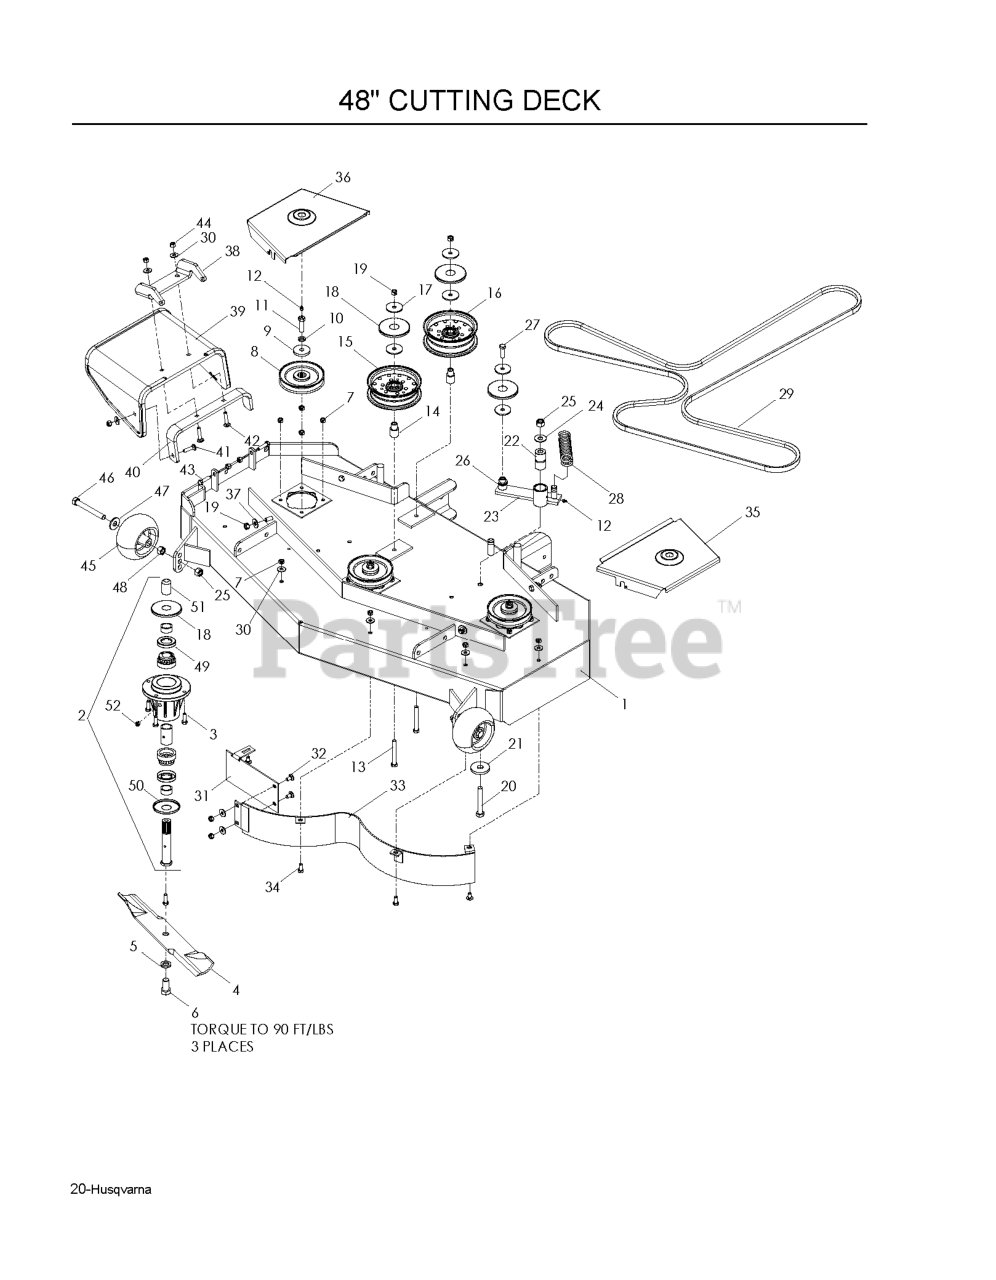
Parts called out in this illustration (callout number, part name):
1	DECK W/DECALS 48"
2	HOUSING ASM, 52/61
3	HCS 5/16C X 1
4	BLADE OEM 16 1/4"
5	LOCKWASHER 5/8
6	HCS 5/8F X 1 1/4
7	NUT 5/16C CENTERLOCK
8	PULLEY 42-48
9	SPINDLE WASHER
10	WASHER 7/16 LOCK
11	HCS 7/16-20 GD 8 SPEC
12	ZERK
13	HCS 3/8C X 3
14	IDLER BUSHING
15	IDLER PULLEY
16	IDLER PULLEY (TALL)
17	WASHER, 3/8 SPEC
18	TOP DUST CAP
19	NUT 3/8C CENTERBLOCK
20	HCS 1/2C X 3 1/4
21	WASHER, SUPPORT
22	PIVOT BUSHING
24	WASHER 1/2 FLAT
25	NUT 1/2-13 HEX NYLOC ZD
27	HCS 3/8C X 1 1/4 GR5
29	BELT, DECK
30	WASHER 5/16 FLAT
31	CENTER BAFFLE 48"
32	CARRIAGE BOLT 5/16C X 5/8"
33	MAIN BAFFLE - 48" DECK BLK
34	HCS 5/16C X 3/4
35	LT 48 SHIELD, ORG
36	RT 48 SHIELD, ORG
37	WASHER 3/8 FLAT
38	PIVOT BRACKET - CHUTE
39	CHUTE, RUBBER DISCHARGE WB
40	BRKT, REINF-CHUTE WB
41	BOLT, CARRIAGE 5/16X1-1/4
42	RHSNB 5/16-18 X 1-1/2 GR 5 ZD
43	HCS 5/16C X 1 1/4
44	NUT 5/16 NYLOC
45	GAUGE WHEEL
46	HCS 1/2-13 X 4 GR 5 ZD
47	WASH USS FLAT 1/2
48	NUT HEX 1/2
49	SHAFT SEAL
50	BOTTOM DUST CAP
52	PLUG-VENTED
